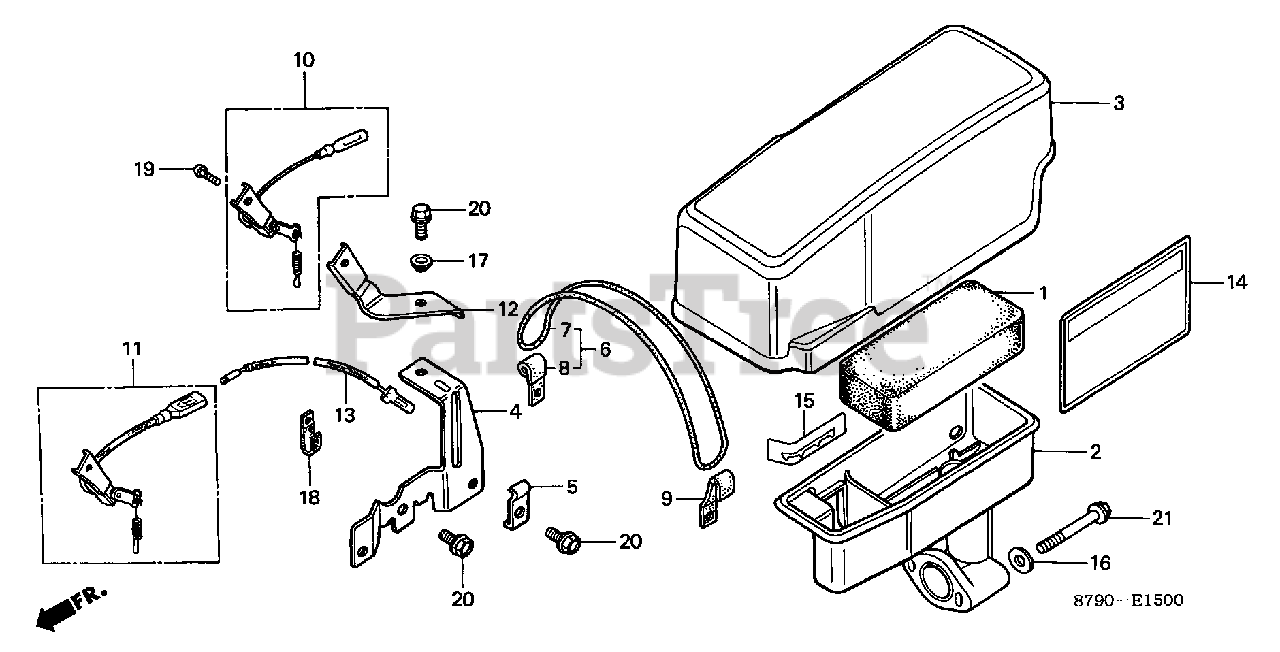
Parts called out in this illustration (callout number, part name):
1	ELEMENT, AIR CLEANER
2	HOUSING, AIR CLEANER
3	COVER, AIR CLEANER
3	COVER, AIR CLEANER (NOT AVAILABLE)
4	STAY, CLEANER CASE
5	HOLDER, WIRE
6	BAND, AIR CLEANER
7	BAND, AIR CLEANER
8	CLIP, AIR CLEANER BAND
9	HOLDER, AIR CLEANER BAND
10	SWITCH ASSY., ENGINE
11	SWITCH ASSY., ENGINE
12	STAY, STOP SWITCH
14	PLATE, DESCRIPTION (NOT AVAILABLE)
15	MARK, CONTROL (NOT AVAILABLE)
16	WASHER (6MM)
17	WASHER, HEADLIGHT CASE
19	SCREW, PAN (3X6)
20	BOLT, FLANGE (6X12)
21	BOLT, FLANGE (6X50)
21	BOLT, FLANGE (6X40)
